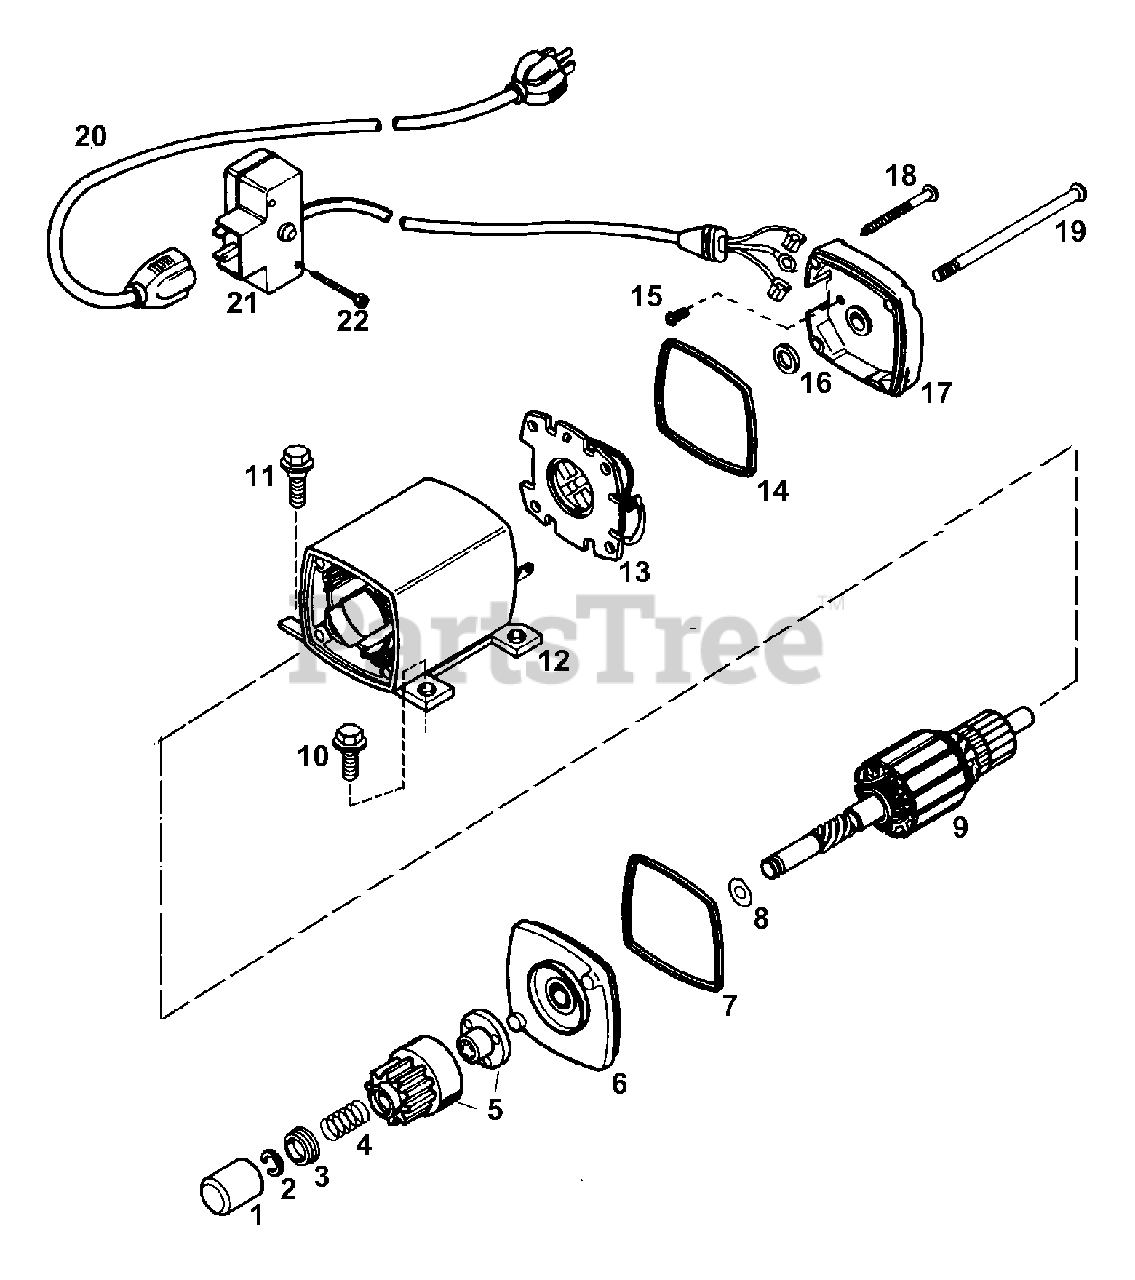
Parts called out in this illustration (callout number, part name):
1	Dust Cover
2	Retainer Ring
3	Spring Retainer
4	Anti-drift Spring
5	Gear & Nut
6	Drive End Cap Ass'y
8	Thrust Washer
10	Screw, Torx T-30, 1/4-20 x 1/2"
11	Screw, 1/4-20 x 1/2"
12	Housing Ass'y
13	Brush Card Ass'y
15	Ground Screw
16	Thrust Washer
17	Commutator End Cap Ass'y
18	Ground Screw
19	Case Bolt
20	Extension Cord (10'6)
21	Switch Box Ass'y
22	Screw, 6-32 x 2 1/2"
